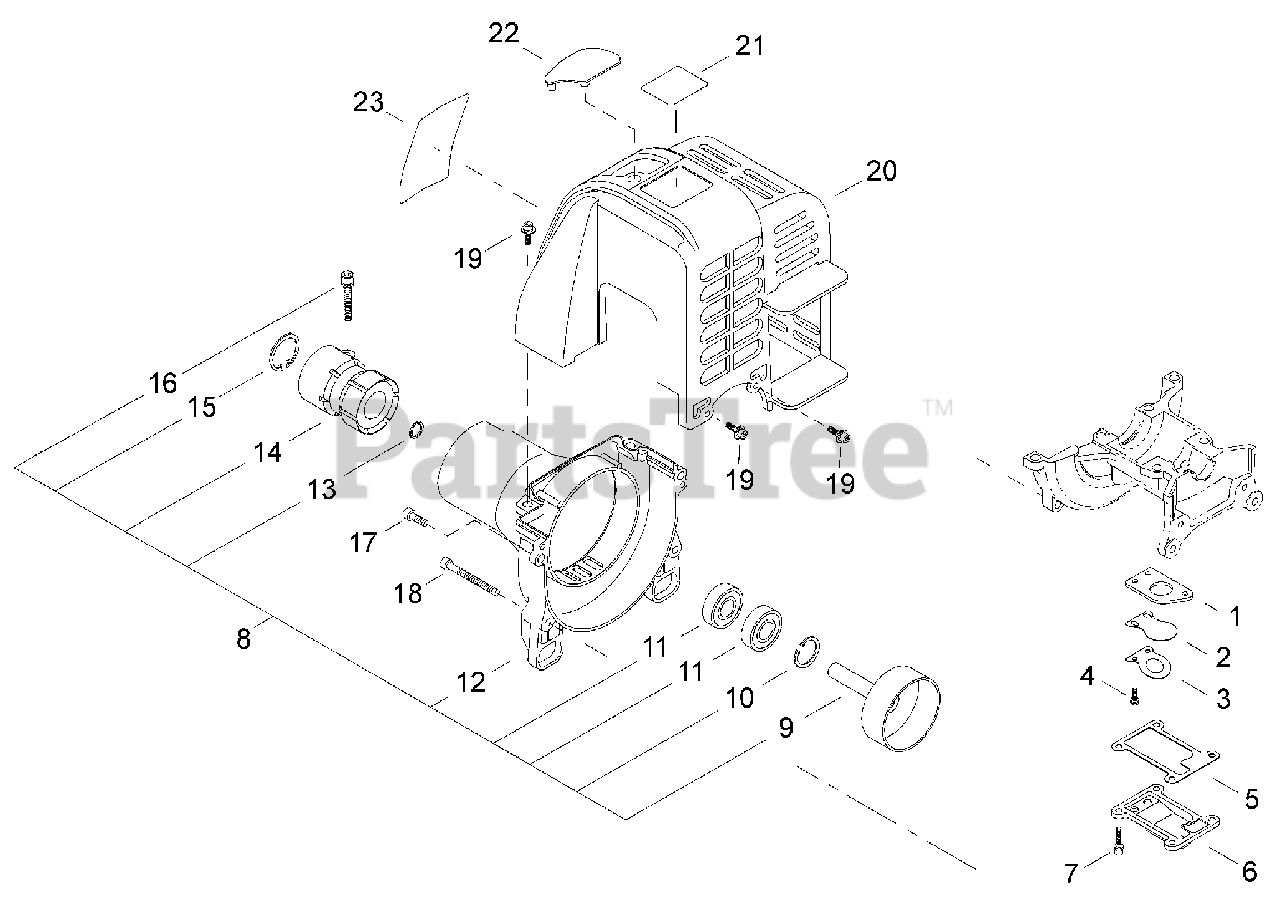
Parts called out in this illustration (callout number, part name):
1	PLATE, REED BACKING
2	VALVE, REED
3	STOP, REED VALVE
4	SCREW M3×10
5	GASKET, REED VALVE
6	COVER, REED VALVE
7	BOLT M4×12
8	COVER ASSY, FAN
9	DRUM, CLUTCH
10	RING, SNAP Ø26
11	BEARING, BALL 6000ZZ
12	COVER, FAN
13	RING, SNAP WR10
14	CUSHION, AV
15	RING, SNAP Ø40
16	BOLT M5×22
17	BOLT 5×16
18	BOLT M5×45
19	BOLT M4×16
20	COVER, ENGINE
21	LABEL, E4 HT4000
22	COVER, SPARK PLUG
23	LABEL, SWISHER E4
